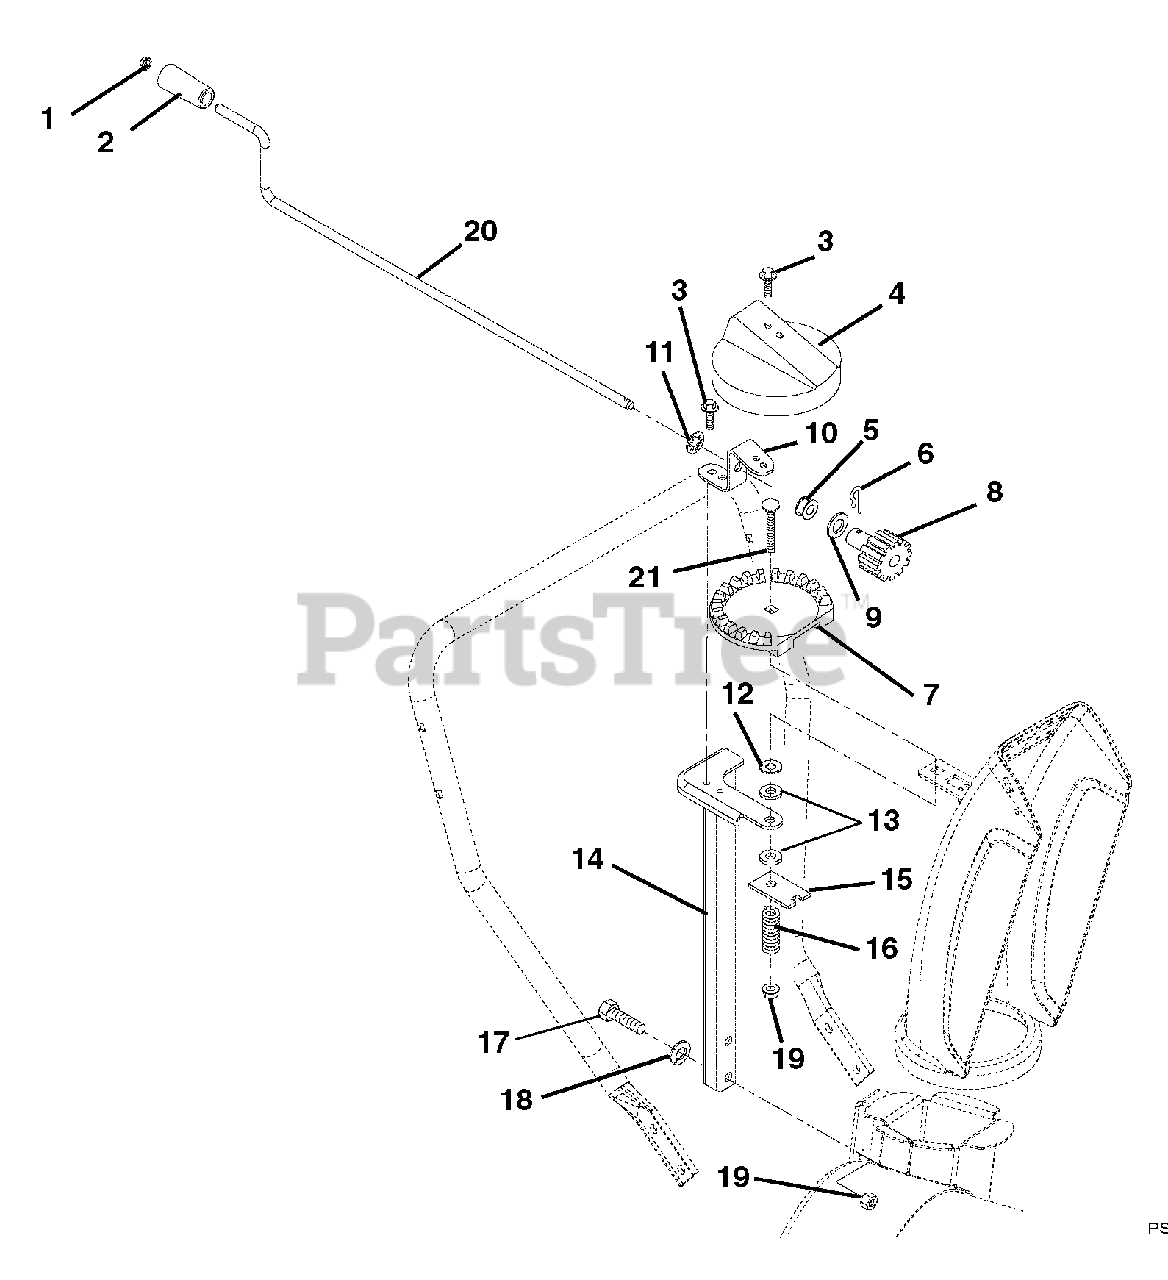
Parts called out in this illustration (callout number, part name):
1	CAP, 3/8 ROD YWZC
2	KNOB, CHUTE CRANK
3	SCR-TAP .25-20X.50 HWH TR YWZ
4	GEAR COVER
5	BUSHING, POLYLINER-.63 SNAPIN
6	PIN, SPRING CLIP
7	CHUTE GEAR
8	PINION GEAR W/BRACKET
9	WSHR-THRST .625 X 1.0 X .03
10	BRACKET, PINION GEAR
11	PUSHNUT .625
12	WSHR-FL-STL .380X1.50X.062 YWZ
13	FRICTION WASHER
14	CHUTE PEDESTAL, TALL COMPACT
15	PLATE, FRICTION
16	SG-COMP .187X.56X1.62
17	@BLT-HEX .38-16X1.75 GR5 YWZC
18	@WSHR-LK .38X.094 REG YWZC
19	@NUT-LK-TOP-FLG .38-16 YWZC
20	CHUTE CRANK,COMPACT 920,XXX HI
21	@BLT-RDHDSQNK .38-16X2.50 G5YZ
